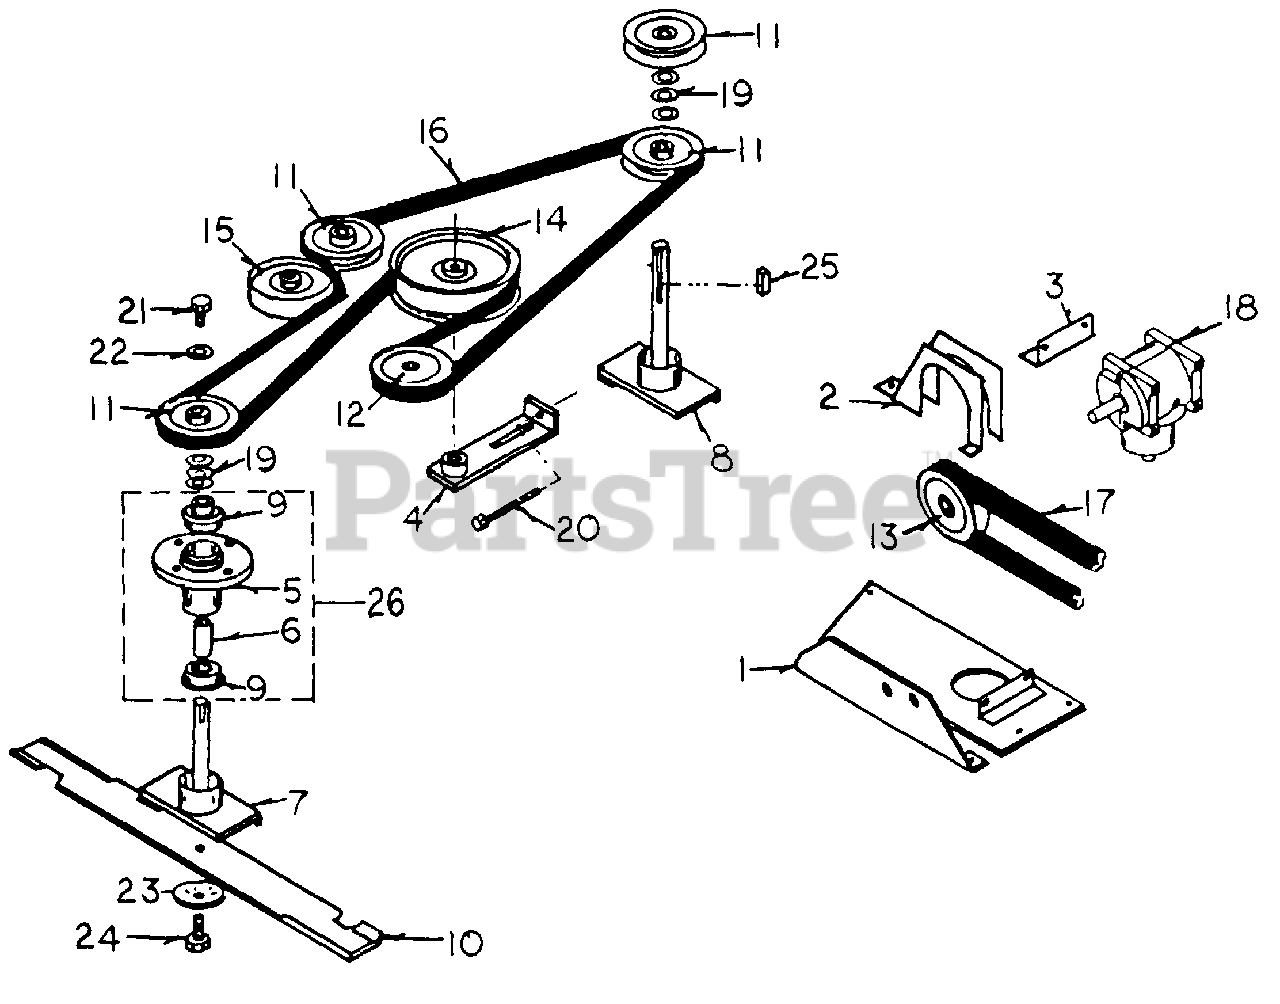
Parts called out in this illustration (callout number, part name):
2	Belt Guard
3	Gearbox Mount Angle
4	Belt Tightener
5	Spindle Housing
6	Spindle Spacer
7	Spindle Shaft
8	Spindle Shaft, Long
9	Spindle Bearing
11	Spindle Pulley
12	Gearbox Pulley, Output
13	Gearbox Pulley, Input
14	Idler Pulley, Large
15	Idler Pulley, Small
17	Deck Drive Belt
20	Adjustment Bolt
21	Hex Ny-Lock Bolt, 5/16-24 x 3/4"
22	Washer, 5/16", 10 GA
24	Hex Bolt, 3/8-24 x 1 1/14"
25	Key Stock, 3/16"
26	Spindle Housing Assembly
